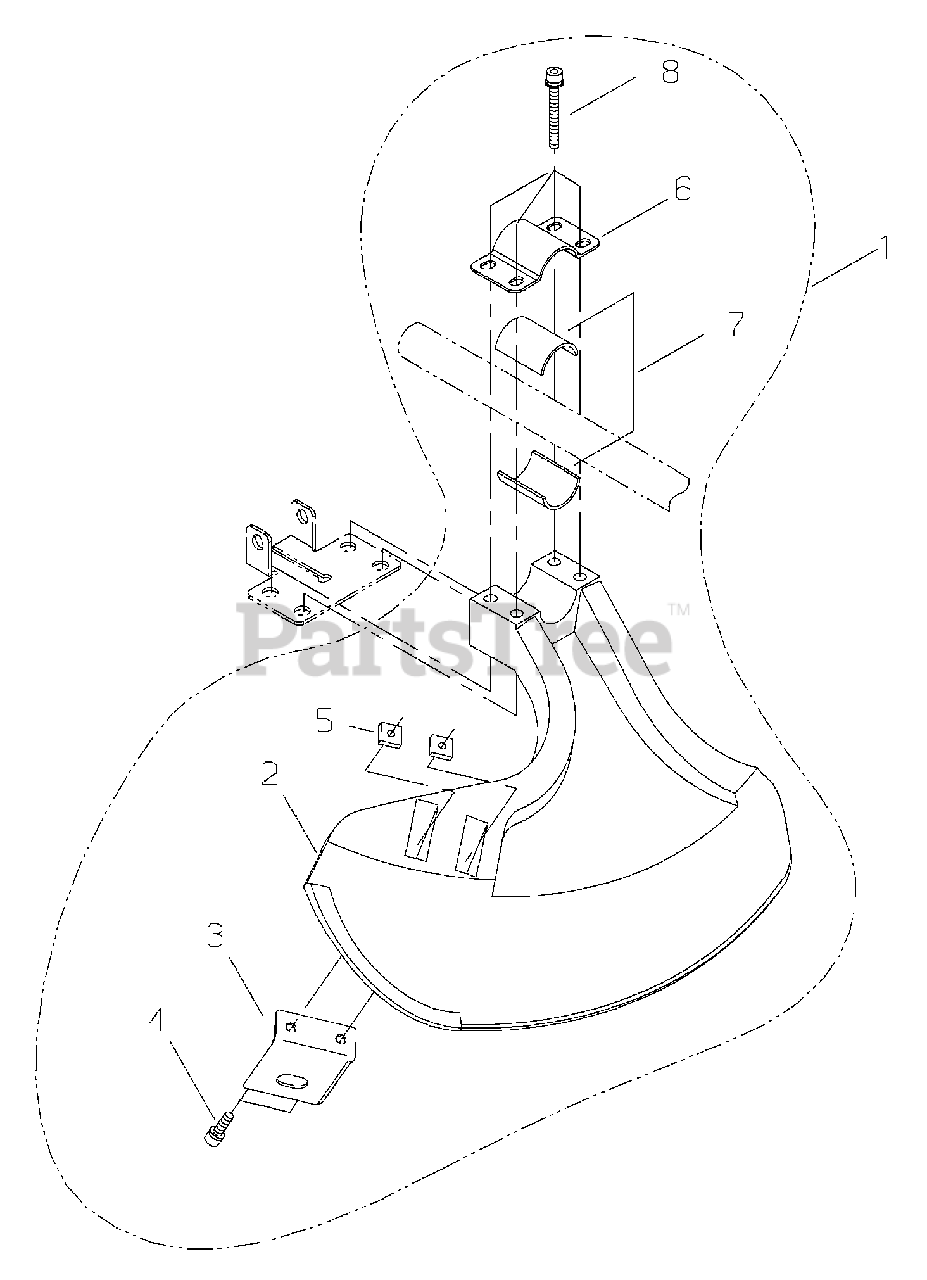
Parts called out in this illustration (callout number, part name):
1	DEBRIS SHIELD KIT
2	SHIELD, DEBRIS
3	CUTTER
4	BOLT M5×16
5	NUT M5
6	CLAMP, UPPER
7	SPACER
8	BOLT M5×45
